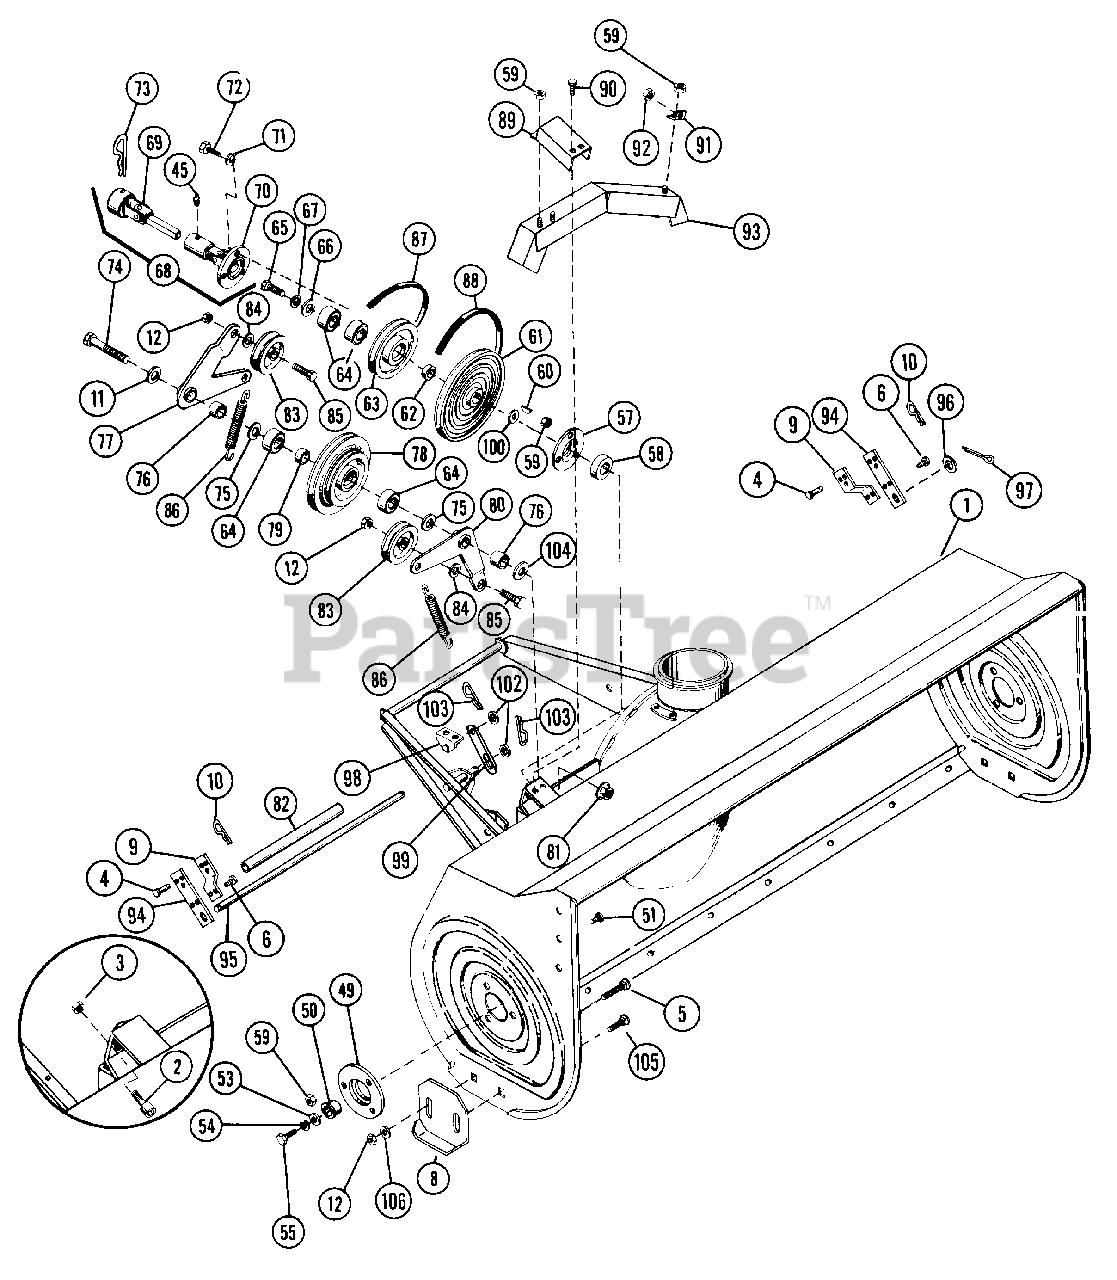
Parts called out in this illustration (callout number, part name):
1	48-INCH SNO THRO HOUSING
2	SCREW, #10-24X.375 CAP
3	NUT, TWIN WHIZ-LOCK #10-24
4	CLEVIS PIN
5	BOLT, 3/8-16X1.00 RD HD SQ NK
6	BOLT, HEX 5/16-18X.50
8	SKID, RUNNER
9	SUPPORT
10	HAIRPIN, INTERNAL 3/32
11	WASHER, .760/.780X1.250X.093
12	NUT, LOCK 3/8-16
45	FITTING, LUBE 1/4-28
49	SUPPORT, BEARING
50	BUSHING, FLANGE 1X1.12X.625
51	BOLT, RIB NECK 1/4-20X.50
53	WASHER, FLAT .515X1.441X.1
54	WASHER, LOCK 1/2 SP HEAVY
55	BOLT, HEX 1/2-13X1.00
57	BEARING, FLANGE
58	BEARING, BALL
59	NUT, LOCK 1/4-20
60	KEY, WOODRUFF .187X.875 HARD #11
61	SHEAVE, 7/8X10
62	SPACER
63	SHEAVE
64	RADIAL BEARING
65	BOLT, HEX 3/8-16X1.00
66	WASHER, FLAT .438X1.000X.083
67	WASHER, LOCK 3/8 REG.
68	SHAFT, UNIVERSAL
69	UNIVERSAL HALF
70	UNIVERSAL HALF
71	WASHER, LOCK 1/4 REG.
72	BOLT, HEX 1/4-20X.875
73	PIN, HAIR INT. .187X3.25
74	BOLT, HEX 3/4-10X5.50
75	WASHER, FLAT .938X1.750X.134
76	SPACER
77	IDLER ARM
78	SHEAVE
79	SPACER
80	IDLER ARM
81	WASHER, .878/.882X2.500X10 GA.
82	TUBE
83	IDLER
84	WASHER, .401/.421X.875X10 GA.
85	BOLT, HEX 3/8-16X1.25
86	SPRING
87	BELT
88	BELT
90	SCREW, TAPTITE 1/4-20X.375
91	CLIP
92	NUT, LOCK 5/16-18
93	BELT GUARD
94	LIFT LINK
95	SHAFT
96	WASHER, FLAT .687X1.312X.122
97	PIN, COTTER .125X1.25
98	LIMITING POST
99	LIMITING ARM
100	WASHER
102	WASHER, FLAT .500X1.250X.083
103	HAIRPIN, INTERNAL
104	WASHER, .750/.760X1.400X.062
105	BOLT, CARRIAGE 3/8-16X.75
106	WASHER, FLAT .406X.812X.065
NS	DECAL, GRAVELY LOGO
NS	DECAL, DANGER FOOT
NS	WARNING WHEEL WEIGHT DECAL
NS	DECAL, AMERICA
